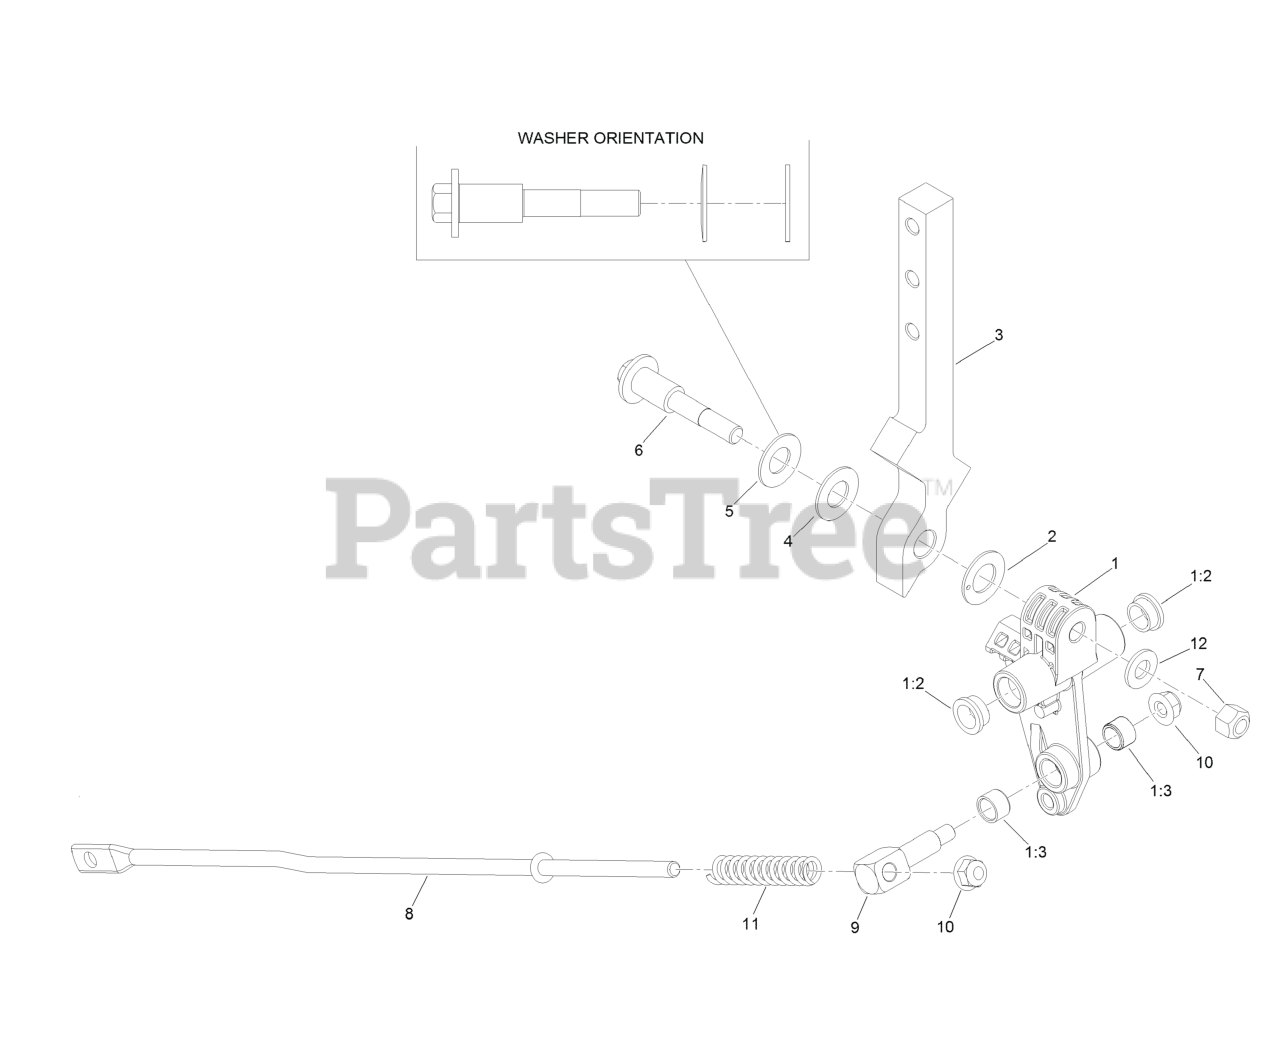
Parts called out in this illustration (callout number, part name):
1	CONTROL ARM ASM
1:2	BUSHING
1:3	BUSHING-SLEEVE
2	WASHER-FRICTION
3	ARM-CONTROL
5	WASHER-BELLEVILLE
6	BOLT-PIVOT
7	NUT-LOCK, CONE
8	LINK-CONTROL
10	NUT-HF, NI
11	SPRING-RETURN, NEUTRAL
12	WASHER-FLAT
